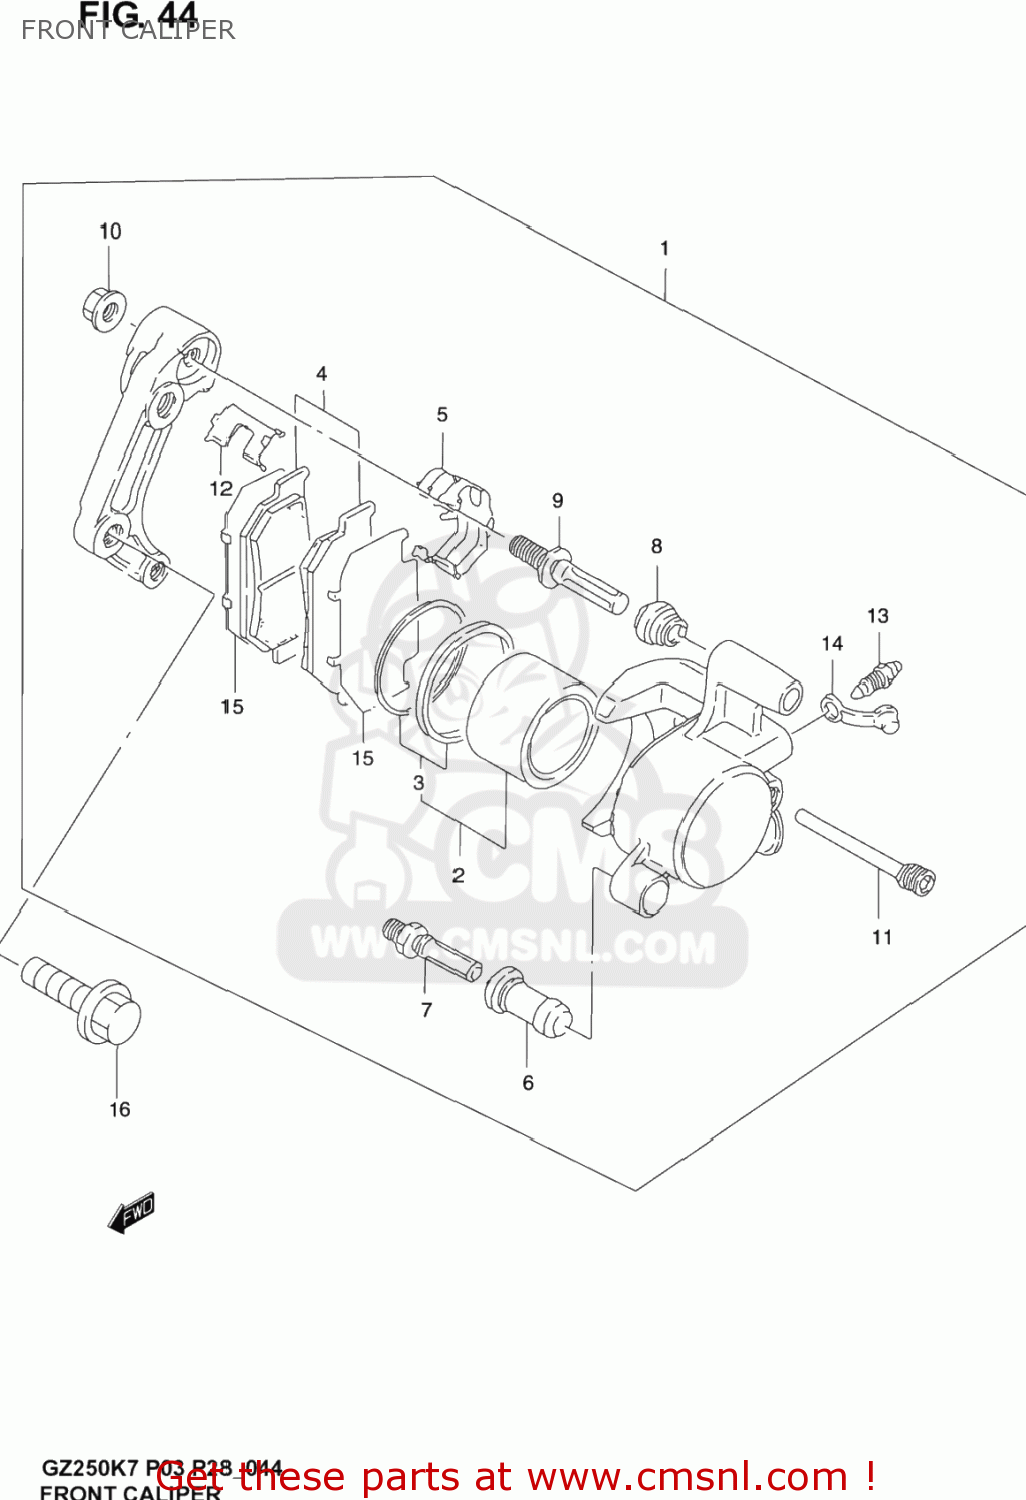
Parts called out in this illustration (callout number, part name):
1	CALIPER ASSY, FRONT LH
2	PISTON SET
3	.SEAL SET, PISTON
4	BRAKEPADSET
5	SPRING
6	BOOT
7	PIN
8	BOOT
9	BOLT
10	BOLT
11	PIN
12	RETAINER
13	BLEEDER
14	CAP
15	SHIM
16	BOLT
